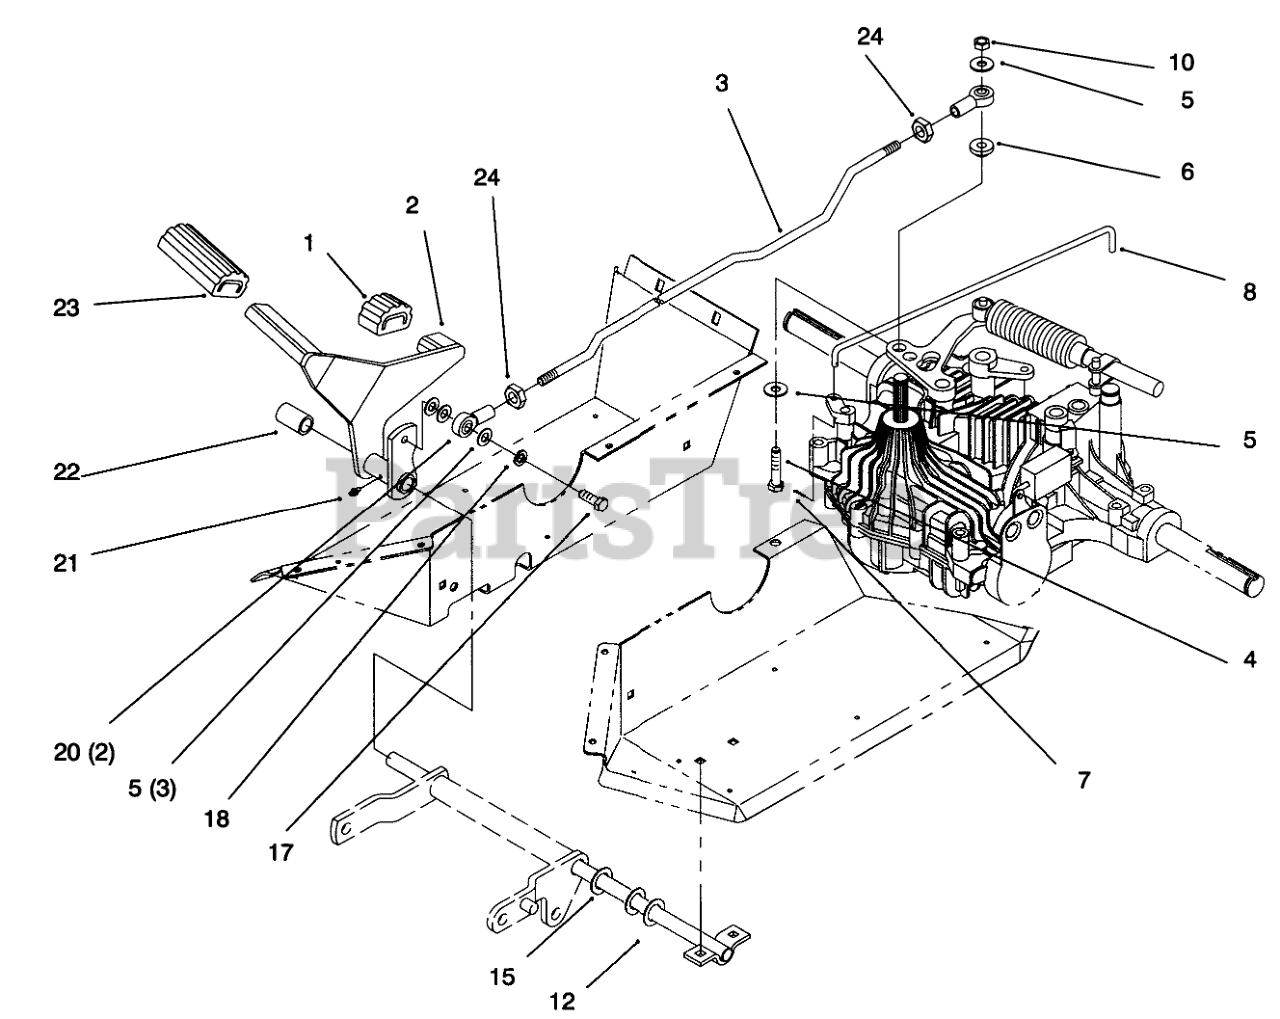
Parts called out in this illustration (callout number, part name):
1	Pad-Pedal Reverse (Only On: 72043, 72063, 72103)
2	Pedal-Hydro (Only On: 72043, 72063, 72103)
3	Rod (Only On: 72043, 72063, 72103)
4	Screw-HH (Only On: 72043, 72063, 72103)
5	WASHER-FLAT
6	Bushing (Only On: 72043, 72063, 72103)
7	Pin-Cotter (Only On: 72043, 72063, 72103)
8	Rod-Bypass (Only On: 72043, 72063, 72103)
10	Nut-Lock (Only On: 72043, 72063, 72103)
12	Washer-Flat (Only On: 72043, 72063, 72103)
15	Spacer (Only On: 72043, 72063, 72103)
17	Screw-HH (Only On: 72043, 72063, 72103)
18	Washer-Lock (Only On: 72043, 72063, 72103)
20	Rod End (Only On: 72043, 72063, 72103)
21	Fitting-Grease (Only On: 72043, 72063, 72103)
22	Spacer-Hydro Pedal (Only On: 72043, 72063, 72103)
23	Pad-Pedal Forward (Only On: 72043, 72063, 72103)
24	Nut-HJ (Only On: 72043, 72063, 72103)
